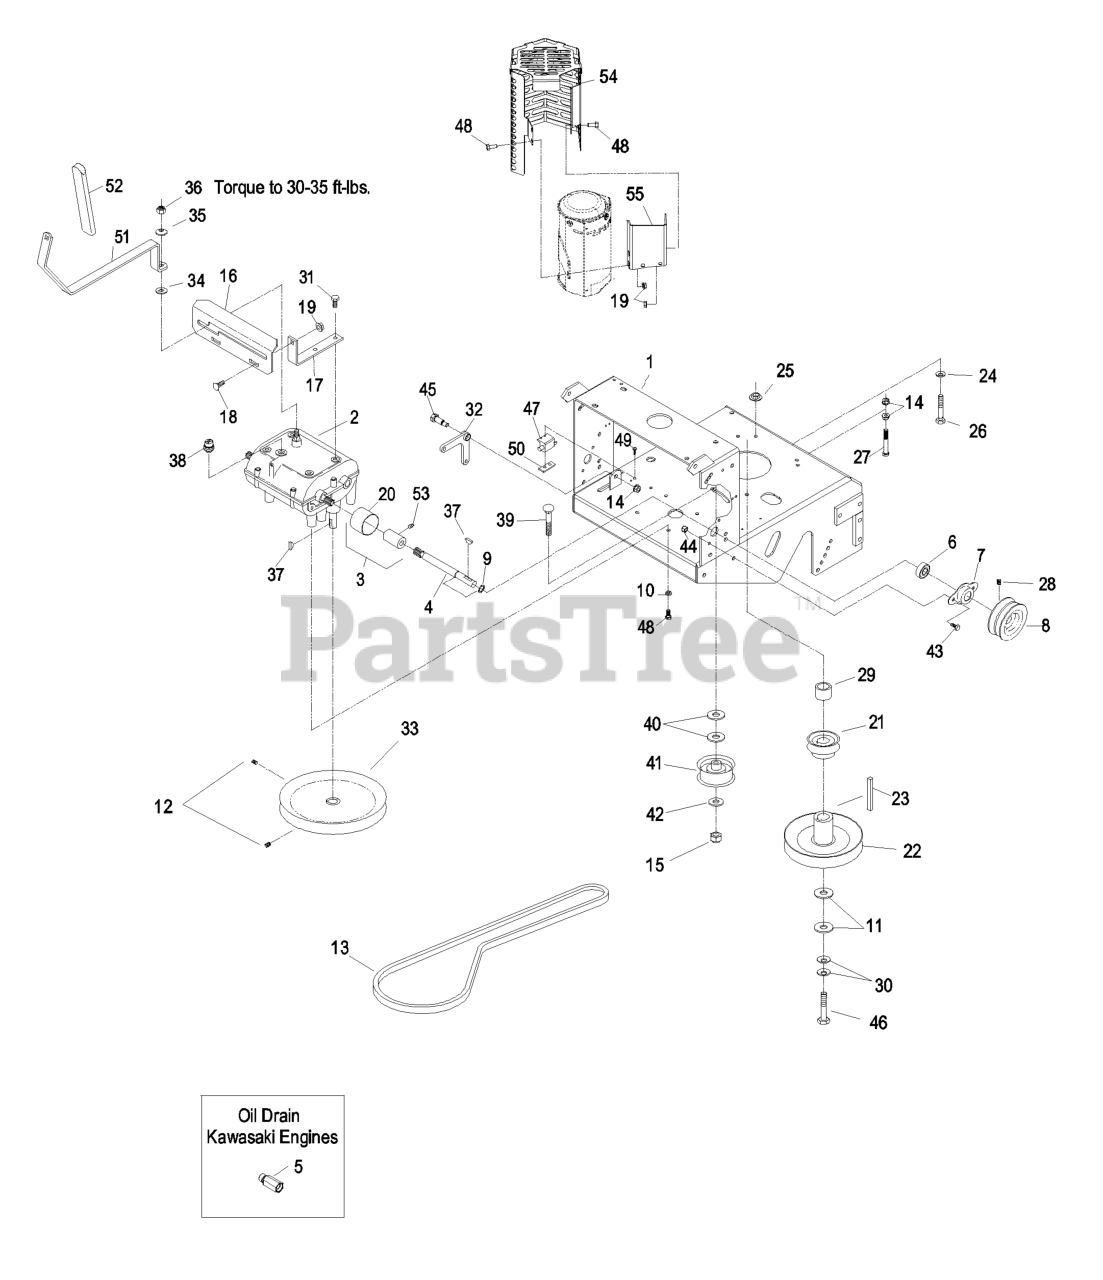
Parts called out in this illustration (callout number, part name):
3	ASM,COUPLER/ZERK
4	SHAFT-TRANSMISSION
5	ADAPTER
6	BEARING-SHAFT
7	FLANGE-OUTPUT
8	SHEAVE-TRANSMISSION
9	RING-RETAINING
10	WASHER-LOCK
12	SCREW-HSH
13	BELT,TRANS DRIVE
14	NUT-HHF, WHIZ
15	NUT-LOCK, NI
16	PLATE,SHIFTER W/DECAL
17	BRACKET-PLATE, SHIFT
18	BOLT-CARR
20	GUARD-COUPLER
21	SHEAVE-TRANSMISSION
24	WASHER-SPRING
26	SCREW-HH
27	SCREW-HH
28	SCREW-SET
29	SPACER-CLUTCH
30	WASHER-SPRING
31	SCREW-HWH, THREAD CUT
32	BELLCRANK
33	SHEAVE-TRANSMISSION
35	WASHER-BELLEVILLE
36	NUT-LOCK
37	KEY-WOODRUFF
38	SWITCH-START, NEUTRAL
39	SCREW-HH
40	WASHER-FLAT
42	WASHER-FLAT
43	SCREW-HH
44	NUT-LOCK, NI
45	BOLT-SHOULDER
46	SCREW-HH
47	SWITCH-OPEN, NORMALLY
48	SCREW-HH
49	SCREW-PPH
50	PLATE-TAPPED
51	ASM,SHIFT LEVER
52	GRIP,FOAM
53	FITTING-GREASE
54	MUFFLER SHIELD ASM
55	BRACKET-MUFFLER
